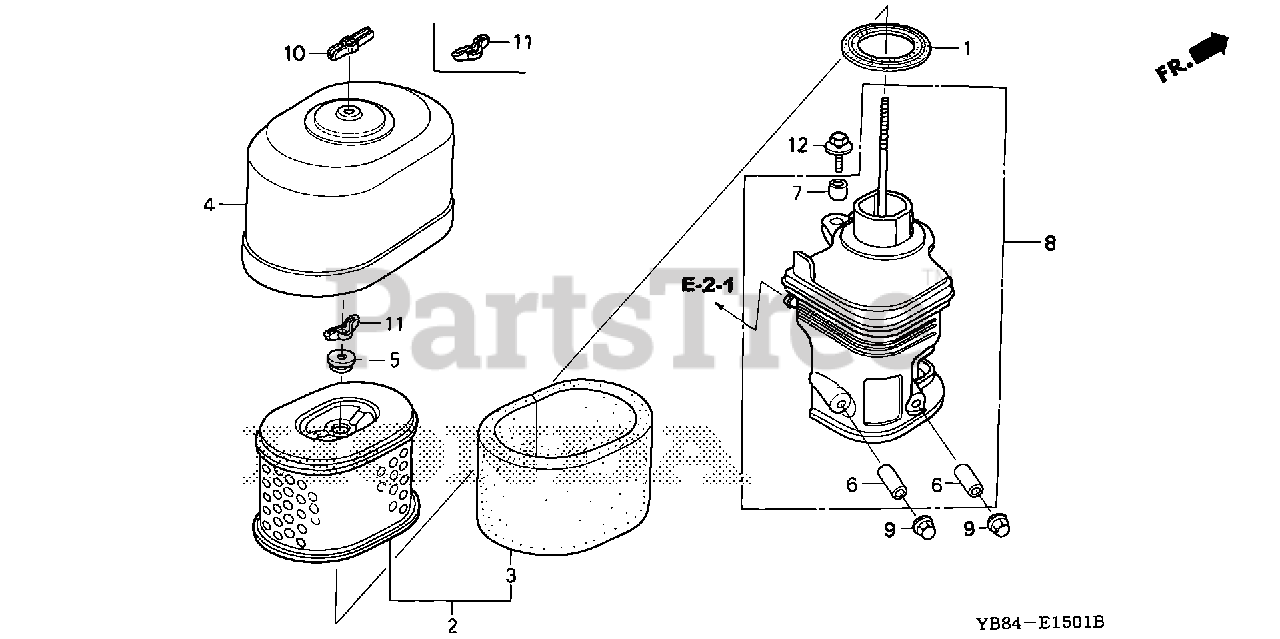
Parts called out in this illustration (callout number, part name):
1	GASKET, ELBOW
2	ELEMENT, AIR CLEANER (DUAL)
3	FILTER (OUTER)
4	COVER, AIR CLEANER (DUAL)
5	GROMMET, AIR CLEANER
6	COLLAR, AIR CLEANER
7	COLLAR B, AIR CLEANER
8	ELBOW, AIR CLEANER
8	ELBOW COMP, AIR/C
9	NUT, FLANGE (6MM)
11	NUT, TOOL BOX SETTING
12	BOLT-WASHER (6X22)
